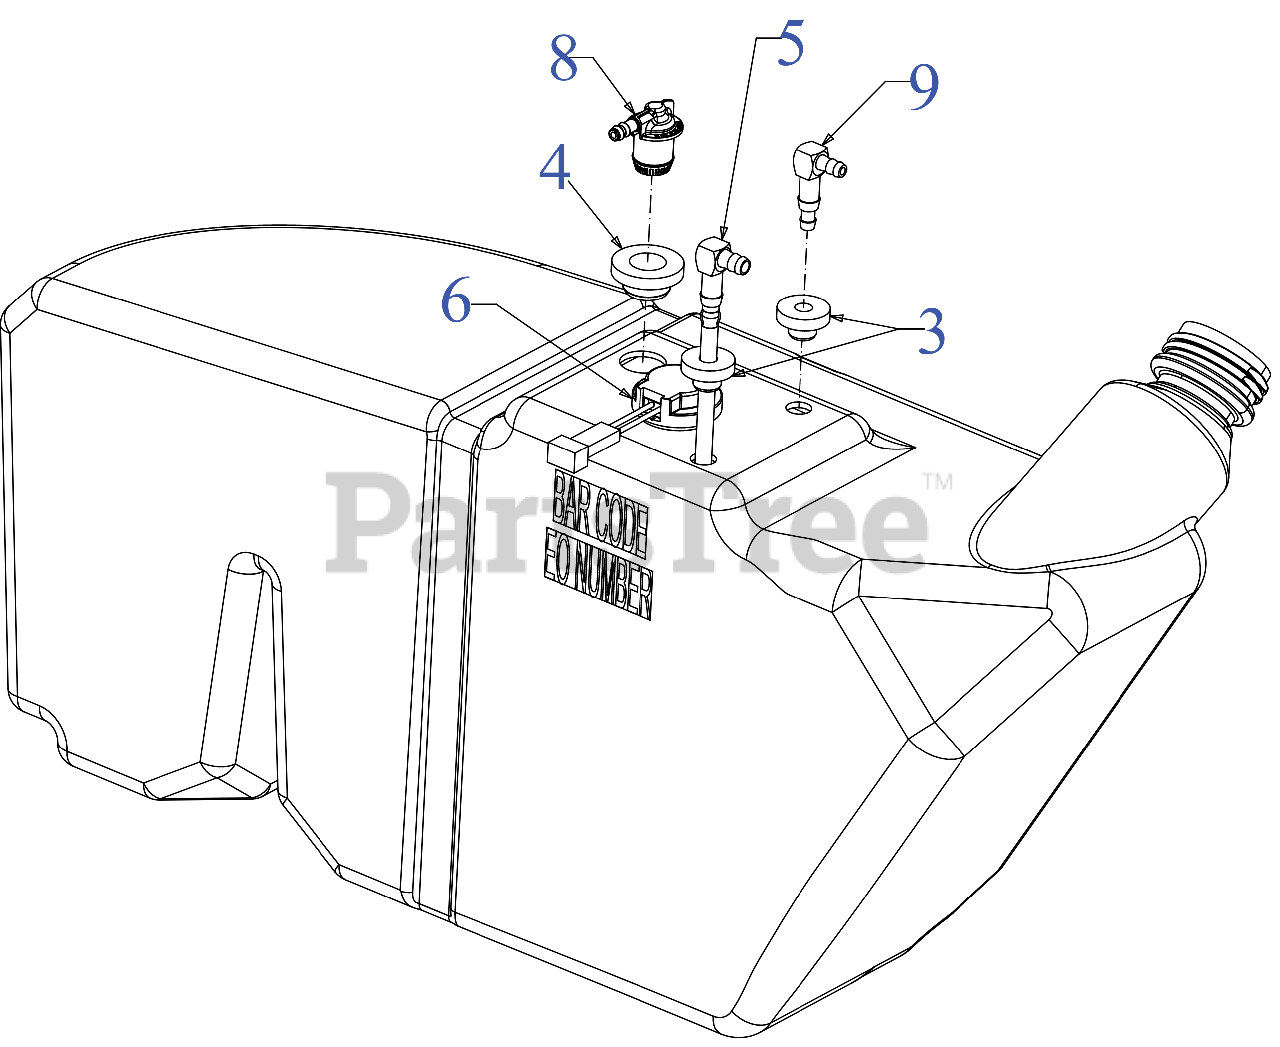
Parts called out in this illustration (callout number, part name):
3	FUEL TANK BUSHING
4	TANK VENT BUSHING
5	FUEL PICKUP FITTING
6	FUEL SENSOR
8	FUEL VENT FITTING
9	FUEL RETURN FITTING
